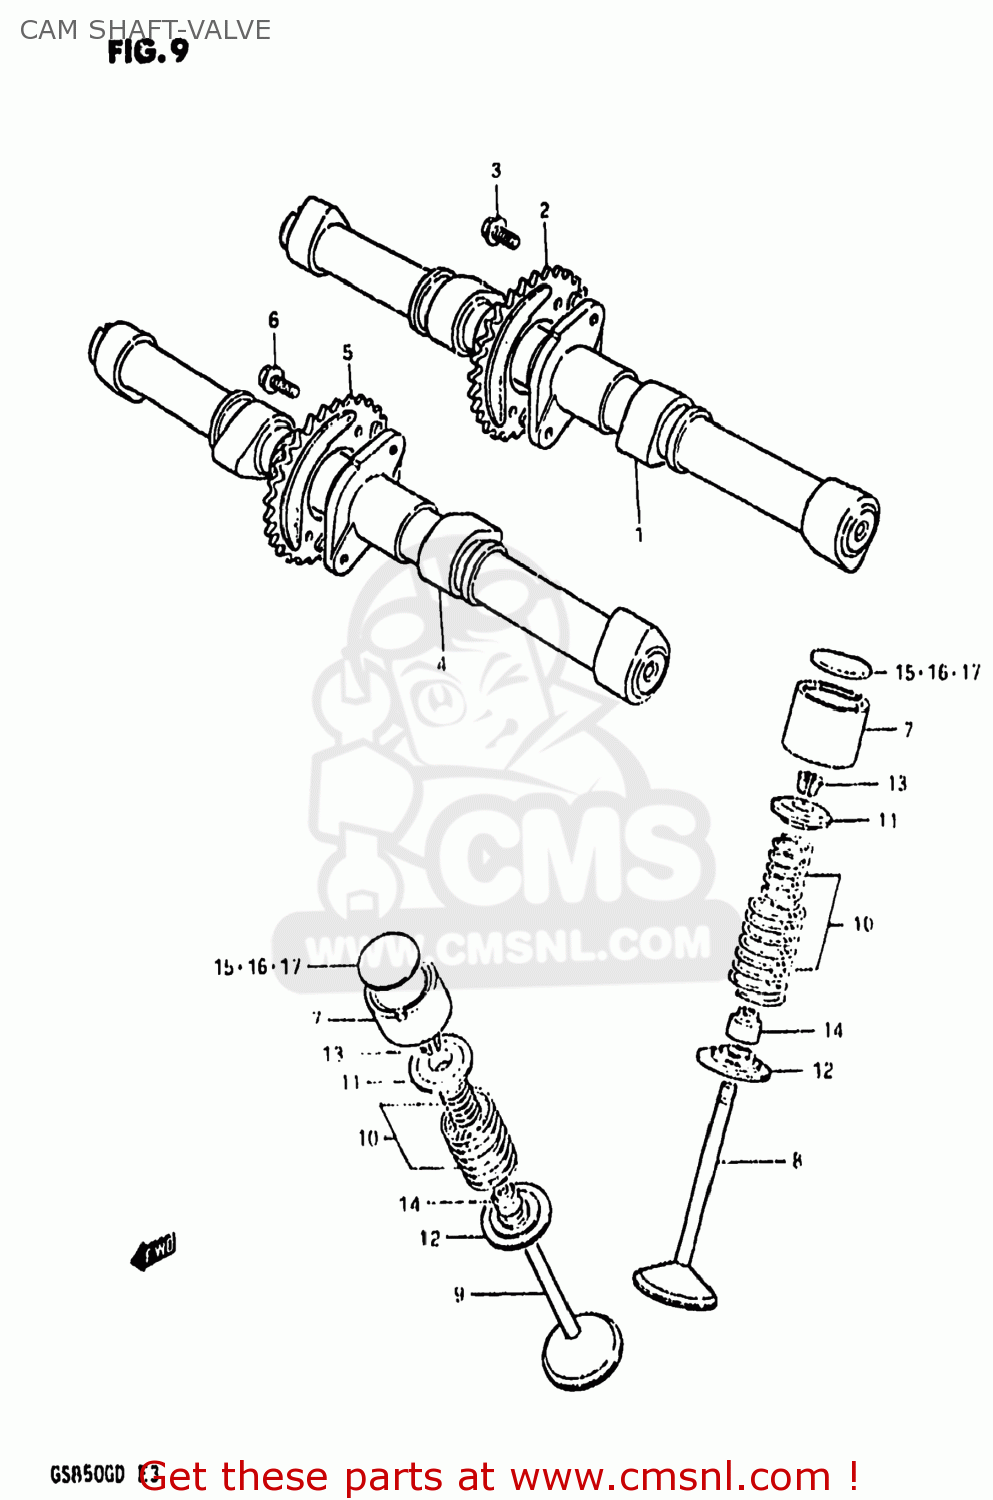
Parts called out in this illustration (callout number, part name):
1	CAMSHAFT,INTAKE
2	SPROCKET,INTAKE CAMSHAFT
3	BOLT(7X11)
4	CAMSHAFT,EXHAUST
5	SPROCKET,EXHAUST CAMSHAFT
6	BOLT(7X11)
7	TAPPET
8	VALVE,INTAKE
9	VALVE,EXHAUST
10	SPRING SET,VALVE
11	RETAINER,VALVE SPRING
12	SEAT,VALVE SPRING
13	COTTER VALVE
14	SEAL,OIL(7X14.4X9)
15	SHIM,TAPPET
16	SHIM,TAPPET
17	SHIM,TAPPET
18	SHIM SET,TAPPET
19	CASE
